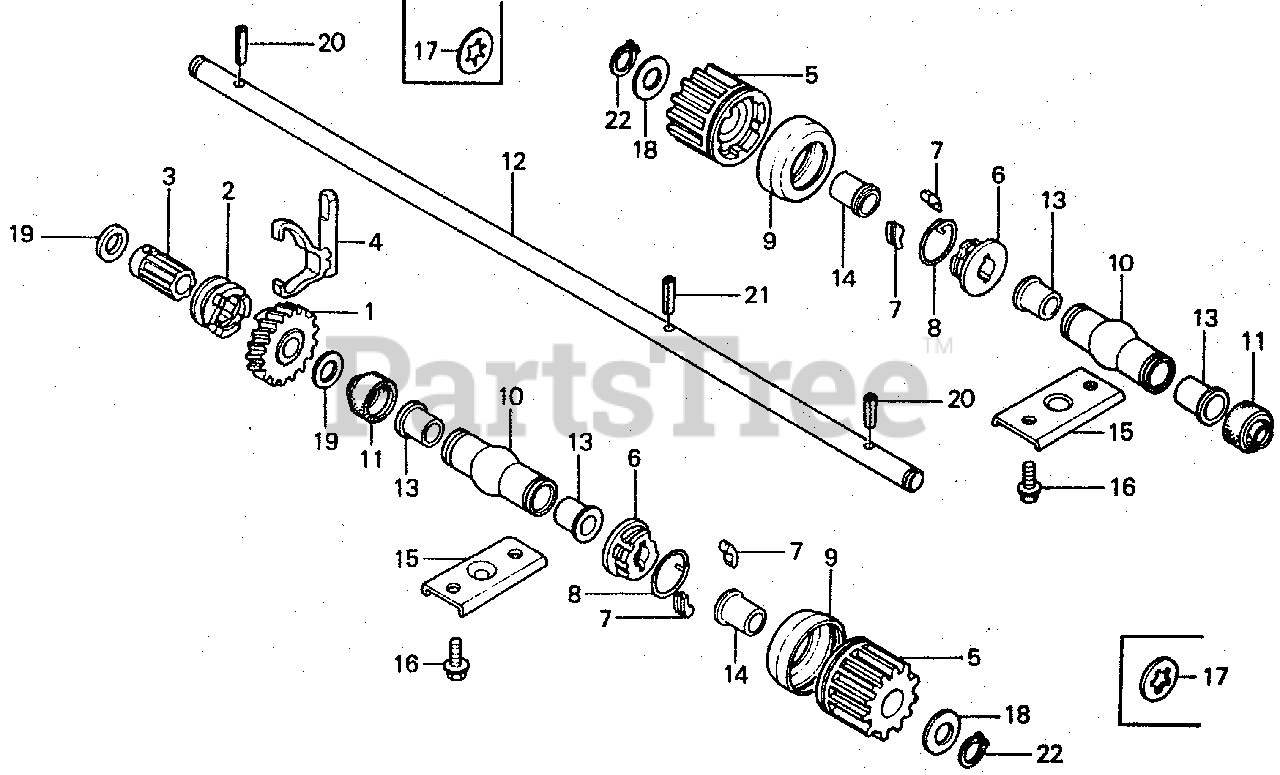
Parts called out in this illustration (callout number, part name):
1	GEAR KIT, DRIVEN
2	CLUTCH, DRIVEN
3	SHAFT, CLUTCH
4	SHAFT, SHIFT
5	GEAR, PINION
6	HOLDER, RATCHET
8	SPRING, RATCHET RETURN
9	CAP, PINION GEAR
10	BOSS, PIPE
11	DUST SEAL
12	DRIVESHAFT
13	BUSH, DRIVESHAFT
14	BUSH, PINION GEAR
15	HOLD, DRIVESHAFT
16	BOLT, FLANGE (6X12) (CT200)
17	WASHER, SPECIAL (12MM)
18	WASHER (12MM)
19	WASHER, THRUST (12MM)
20	PIN, SPRING (4X18)
21	PIN, SPRING (5X18)
22	CIRCLIP (OUTER) (12MM)
